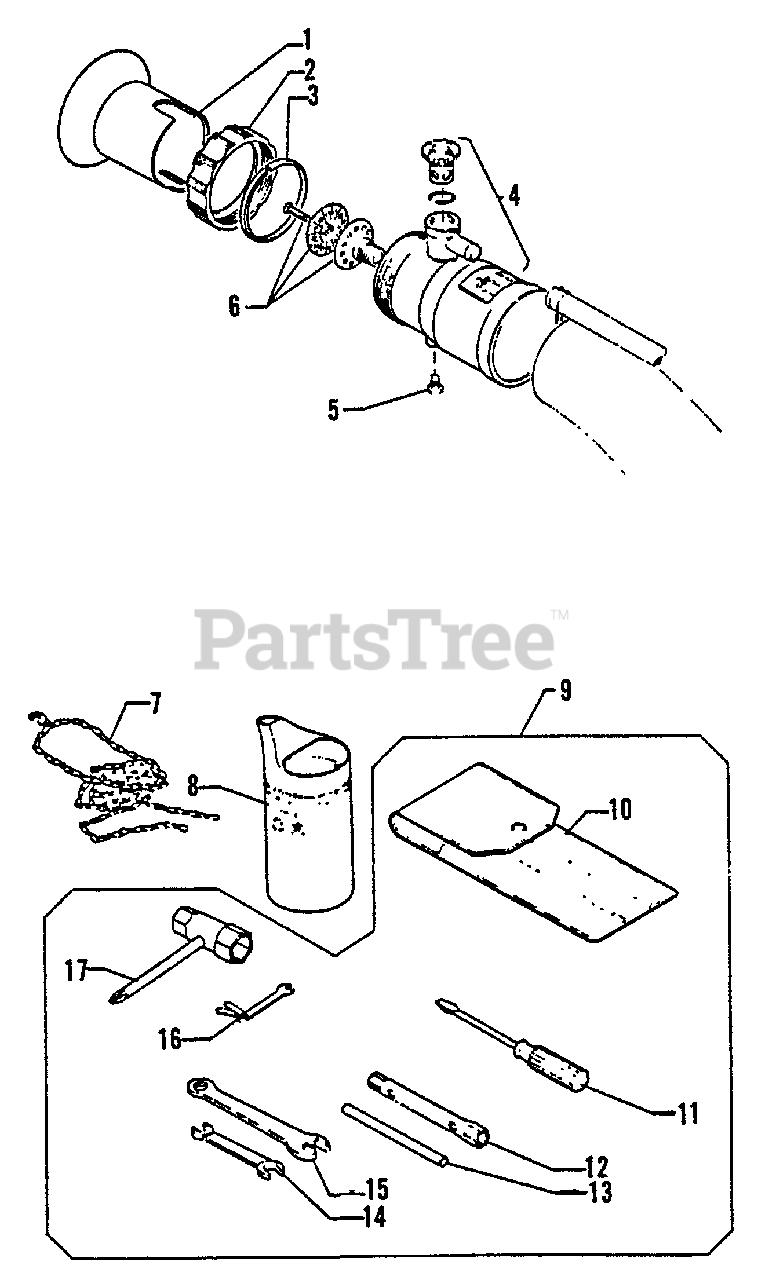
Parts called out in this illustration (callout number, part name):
1	COLLAR, NOZZLE
3	RING, NOZZLE
4	ADJUSTER, VOLUME
5	SCREW 5×12
6	NOZZLE ASSY
7	CHAIN
8	MIXER, FUEL
9	TOOL SET
10	BAG, TOOL
11	SCREWDRIVER - SLOT HEAD
12	WRENCH 8×10
13	ROD, HANDLE
14	SPANNER 8×10
15	SPANNER 10×21
16	MAGNETO SPANNER
17	BOX SPANNER 14×21
